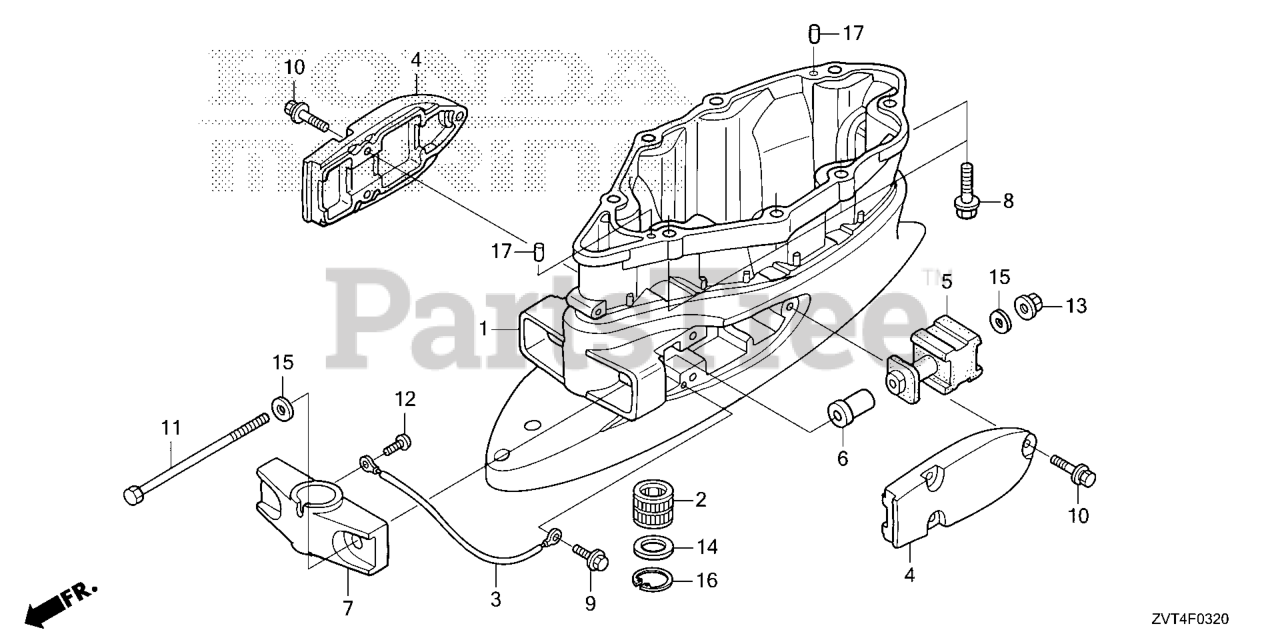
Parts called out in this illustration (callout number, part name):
1	CASE, EXTENSION *NHB14M* (AQUA MARINE SILVER METALLIC)
1	CASE,EXTENS*NH565*
2	BUSH, VERTICAL SHAFT
3	WIRE, LEAD (1.5X137MM)
4	HOUSING, MOUNTING (LOWER) *NHB14M* (AQUA MARINE SILVER METALLIC)
4	HSG,LWR MT*NH565*
5	RUBBER, MOUNT (LOWER)
6	COLLAR, MOUNTING (LOWER)
7	HOUSING, CENTER MOUNTING (LOWER) *NHB14M* (AQUA MARINE SILVER METALLIC)
7	HSG,LWR MT*NH565*
8	BOLT, FLANGE (10X40)
9	BOLT, FLANGE (6X12)
10	BOLT-WASHER (8X30)
11	BOLT, HEX. (12X225)
12	SCREW, PAN (6X8)
13	NUT, FLANGE (12MM)
14	WASHER (26MM)
15	WASHER, PLAIN (12MM)
16	CIRCLIP (INNER) (40MM)
17	PIN, DOWEL (6X10)
